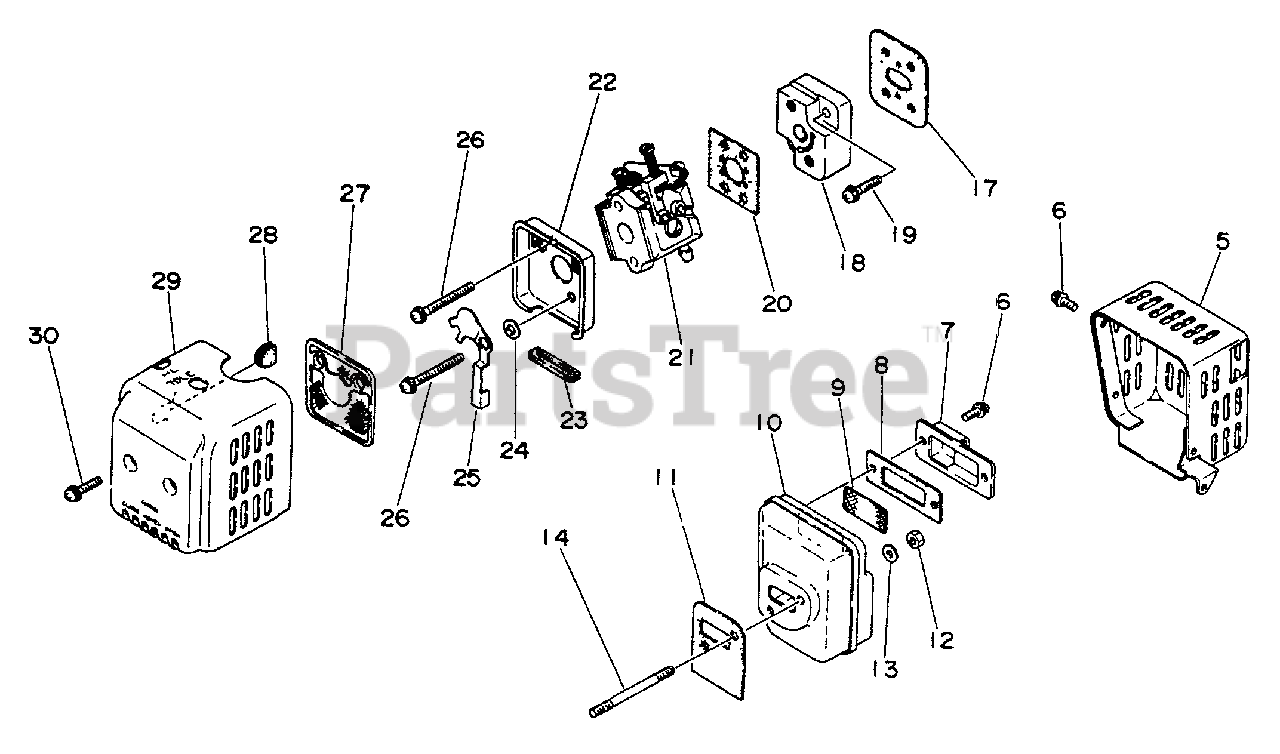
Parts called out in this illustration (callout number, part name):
5	COVER, EXHAUST
6	SCREW 4×10
7	SCREEN HOLDER
8	GASKET, EXHAUST
9	SCREEN, SPARK ARRESTER
10	MUFFLER
11	GASKET, EXHAUST
12	LOCKNUT - 5
13	WASHER 5.5×12×0.8
14	BOLT, STUD
17	GASKET, INTAKE
18	INSULATOR
19	SCREW 5×20
20	GASKET, INTAKE
21	CARBURETOR - WA-138A
21	CARBURETOR - WA-143
22	CASE, AIR FILTER
24	WASHER 5.2×8×0.8T
25	SHUTTER, CHOKE
26	SCREW 5×40
27	FILTER, AIR
28	PLUG
29	COVER, AIR FILTER
30	SCREW 4×18
